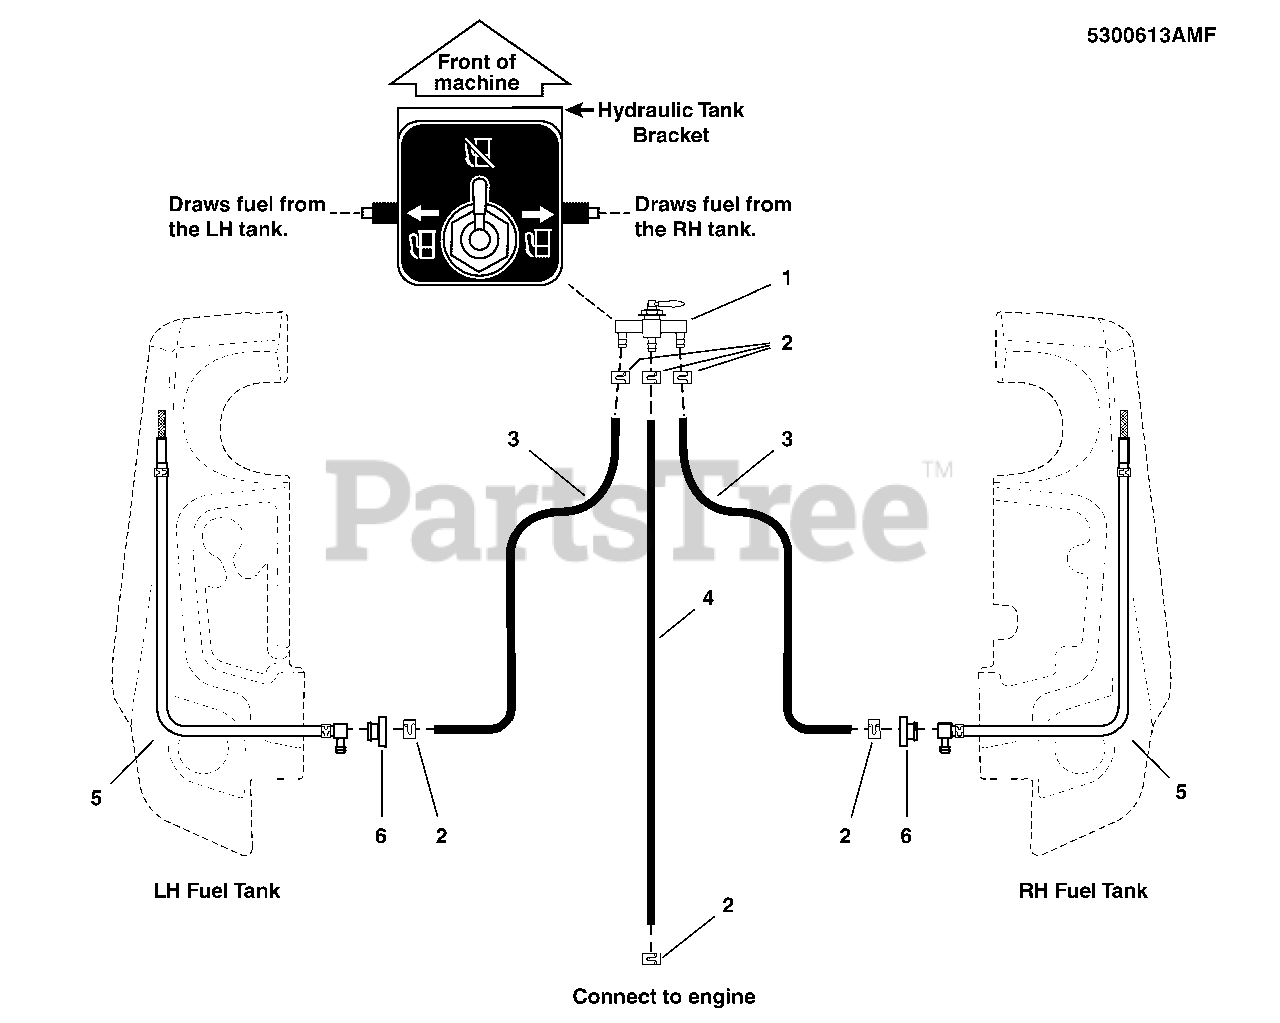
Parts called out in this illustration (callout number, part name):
1	VALVE, FUEL, STR. OUTLET
2	CLAMP, HOSE, EXTERNAL, 1/2 - RED
3	HOSE, 1/4" FUEL, 27.00"
4	LINE-FUEL
5	PICKUP TUBE ASM, FUEL TANK, 23" (SV)
6	BUSHING-FUEL TANK RED RUBBER (SV)
